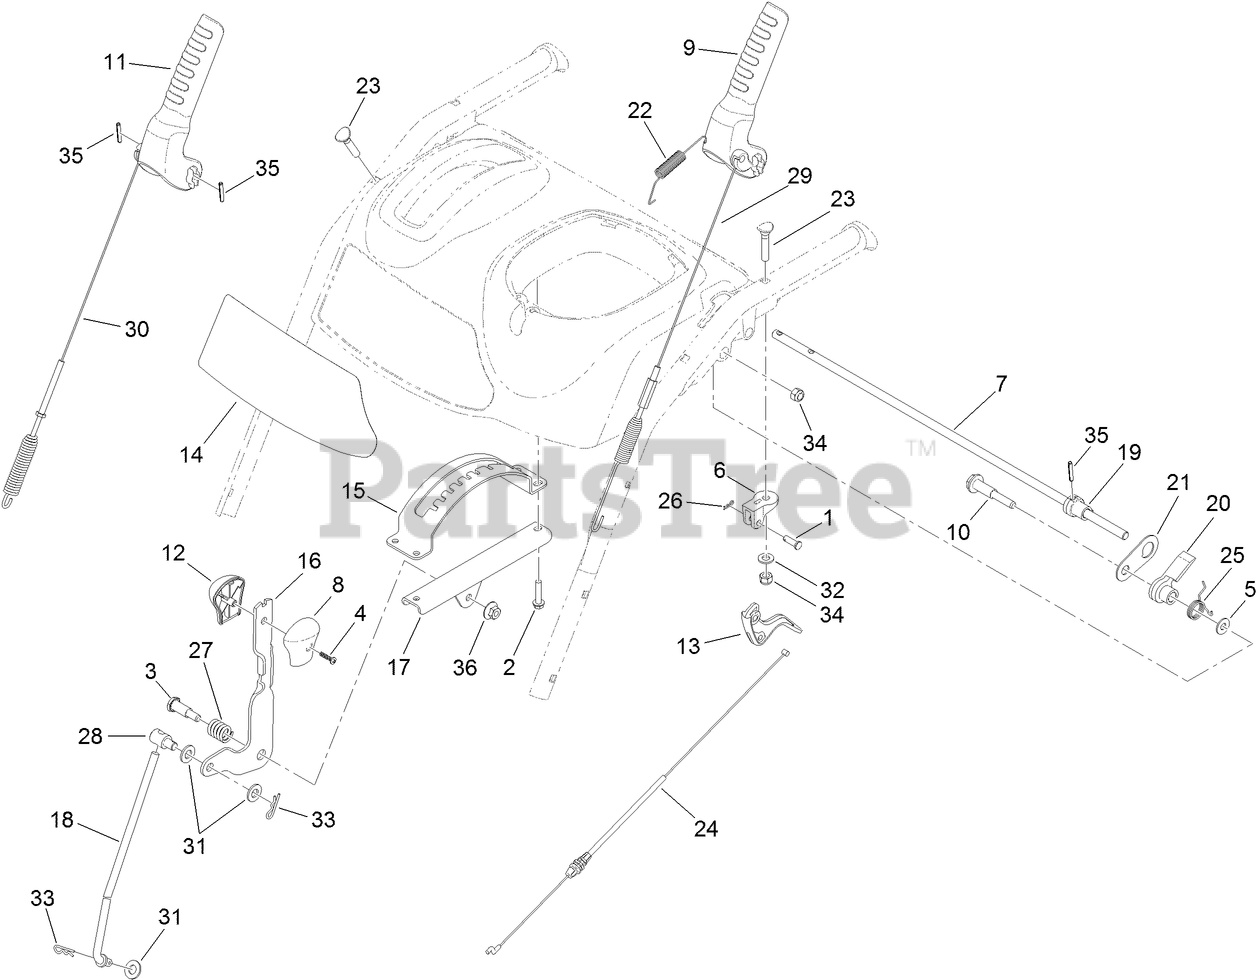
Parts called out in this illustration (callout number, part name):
1	PIN-CLEVIS
2	SCREW-PLASTITE
3	SCREW-SHOULDER
4	SCREW-PPH
5	WASHER-FLAT
6	MOUNT-LEVER, CLUTCH
7	ROD-LOCKOUT
8	KNOB-SHIFT, LH
9	LEVER-TRACTION
11	LEVER-AUGER
12	KNOB-SHIFT, RH
13	LEVER-CLUTCH
14	DECAL-CONTROL PANEL
15	GUIDE-SELECTOR, SPEED
16	SELECTOR-SPEED
17	MOUNT-SELECTOR, SPEED
19	CAM-LOCKOUT
20	LATCH-LOCKOUT
21	LINK-LOCKOUT
22	SPRING-TENSION
23	SCREW-HANDLE
24	CABLE-CLUTCH
25	SPRING-TORSION
26	PIN-HAIR
28	TRUNNION-ROD
29	CABLE-TRACTION
30	CABLE-AUGER
31	WASHER-FLAT
32	WASHER-FLAT
34	NUT-LOCK, NI
35	PIN-SPRING
36	NUT-HF
